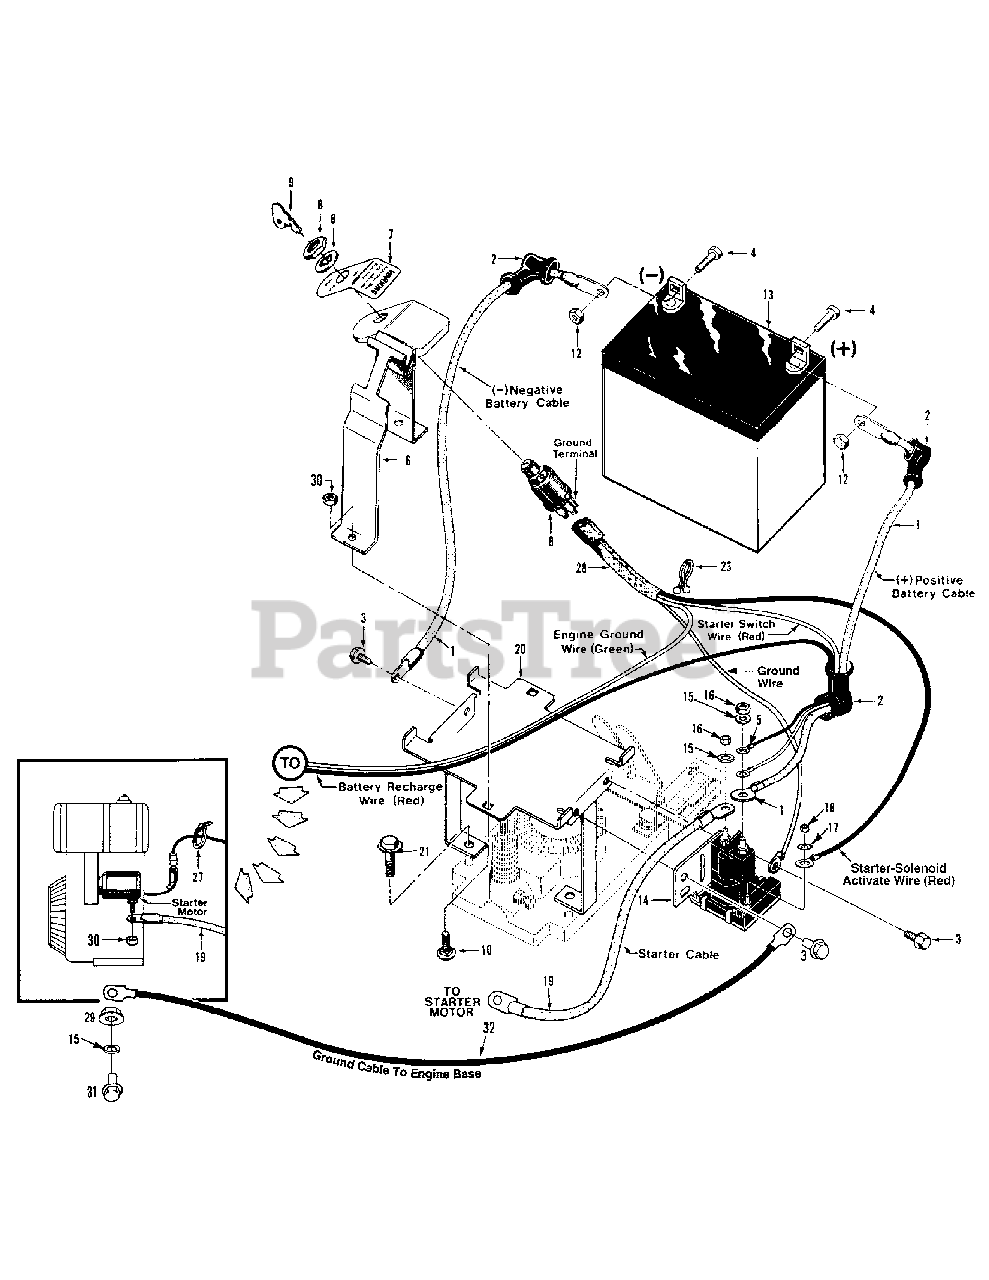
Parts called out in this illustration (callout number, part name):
1	Cable-battery, positive and negative terminals
2	Boot-terminal insulating
3	Screw-self-threading, 1/4-20 x 1/2"
4	Bolt-hex hd., 1/4-20 x 5/8"
5	Wire-recharge (red)
6	Battery Hold-down Clamp- with attached Key Switch Plate
7	Decal-ignition switch instructions
8	Key Switch-includes two ignition keys (Ref. No. 9) one lockwasher, and one mounting nut
9	Key-ignition, one pair
10	Bolt-carriage, 1/4-20 x 1-1/4"
11	Lockwasher-spring lock, 1/4"
12	Nut-hex, 1/4"-20
13	Battery-12 volt, 270 CCA
14	Solenoid-starter, includes nuts and washers for cables and wires
15	Lockwasher-5/16"
16	Nut-hex, 5/16"-24
17	Lockwasher-external tooth, #10
18	Nut-hex, #10-32,
19	Cable-solenoid to starter motor
20	Battery Bracket
21	Bolt-flanged hex hd., 3/8-16 x 1-1/2"
23	Tie-plastic, wire retaining
27	Tie-plastic
28	Wire Harness & Connecting Terminal Assembly
29	Nut-flange lock, 5/16" 18
30	Locknut-hex, 1/4"-20
32	Cable-ground, solenoid to engine block
33	Bolt-flange lock, 5/16-18 x 1"
